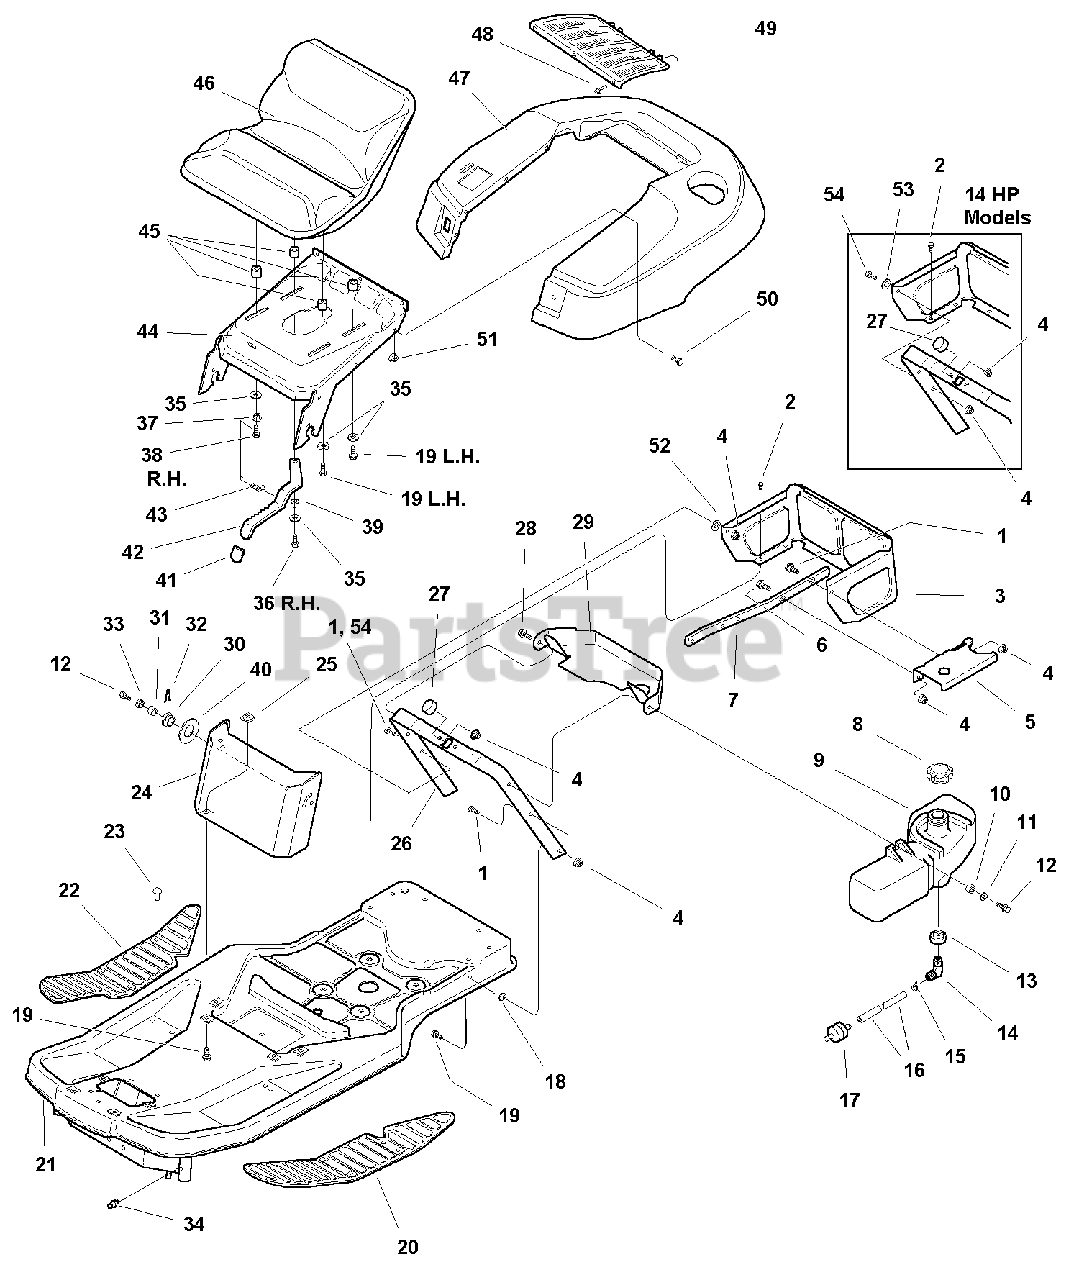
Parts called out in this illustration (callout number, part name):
1	CAPSCREW, Hex Head, 5/16-18 x 1
2	CAPSCREW, Hex Head, Taptite, 1/4-20 x 1/2
3	SHROUD, Rear
4	NUT, Hex, Flange, Whizlock, 5/16-18
5	SUPPORT, Fuel Tank
6	CARRIAGE BOLT, 5/16-18 x 3/4
7	STRAP, Fuel Tank, Brace
8	CAP, Fuel Tank, Vented
10	SPACER, 21/64 x 1/2 x 21/64
11	WASHER, Plain, 13/32 x 7/8 x 5/64
12	CAPSCREW, Taptite, 5/16-18 x 1-1/ (14 & 16HP Models)
12	CAPSCREW, Hex, Taptite, 5/16-18 x 1 (11 & 13 HP Models)
13	BUSHING, Rubber
15	CLAMP, Hose
16	HOSE, Fuel Line
17	FILTER, Fuel
18	PUSH NUT, 5/16
19	CAPSCREW, Hex Head, Whizlock, 5/16-18 x 3/4
20	PAD, Foot Rest, LH
21	FRAME ASSEMBLY (Includes Ref. No. 2)
22	PAD, Foot Rest, RH
24	PANEL, Front
25	PAL NUT, 5/16-18
26	SUPPORT, "U" Seat (14 & 16 HP Models)
26	SUPPORT, "U", Seat (11 & 13 HP Models)
27	BUMPER, Rubber
28	CAPSCREW, Hex Head, Taptite, 5/16 x 1/2
29	DUCT, Air Inlet (11 & 13 HP Models)
29	DUCT, Air Inlet (14 & 16 HP Models)
30	SPACER, Plastic
33	PIVOT, Hood
34	FITTING, Lube
35	WASHER
36	CAPSCREW, Hex Head, 5/16-18 x 1-1/2
37	NUT, Hex, 5/16-18
38	CAPSCREW, 5/16-18 x 1-1/4
41	CAP, Black, Vinyl
42	ADJUSTER, Seat
43	SPRING, Extension
44	SUPPORT, Seat
46	SEAT ASSEMBLY
47	DECK, Seat, Orange
47	DECK, Seat, Red
49	SCREEN, Seat Deck Top
50	CAPSCREW, Hex Head, Whizlock, 1/4-20 x 5/8
51	NUT, Hex, Flange Lock, 1/4-20
52	WASHER, 5/16
53	SPACER (14 HP Models)
54	CAPSCREW, Hex Head, 5/16-18 x 1-3/4 (14 & 16 HP Models)
